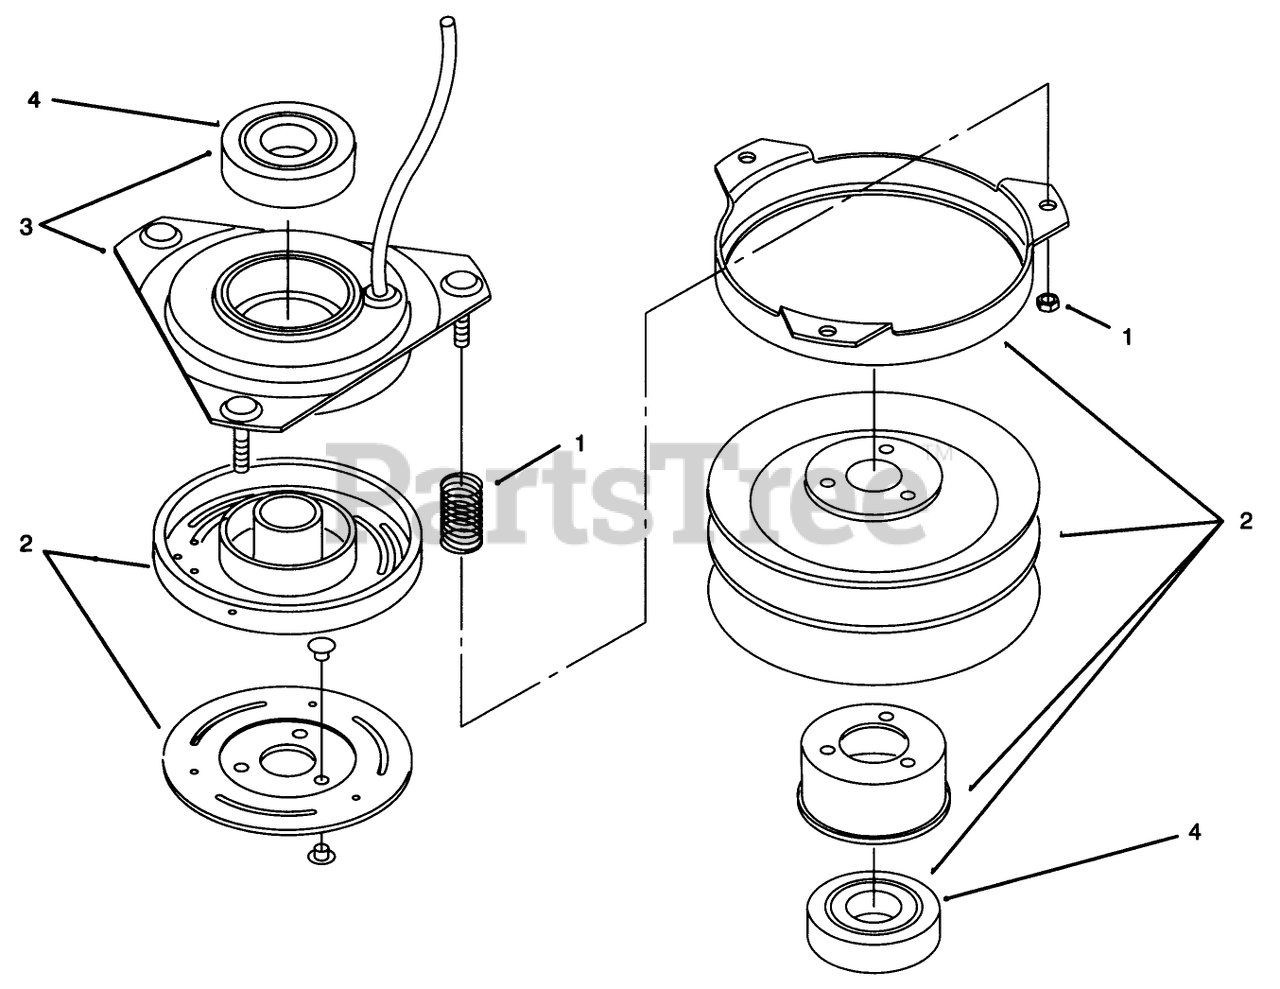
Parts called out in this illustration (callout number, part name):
1	ACCESSORY PKG SRVC PART
2	ROTOR & ARMATURE ASSY
3	FIELD ASSY (SRVC PART)
4	BEARING-ELEC CLUTCH
